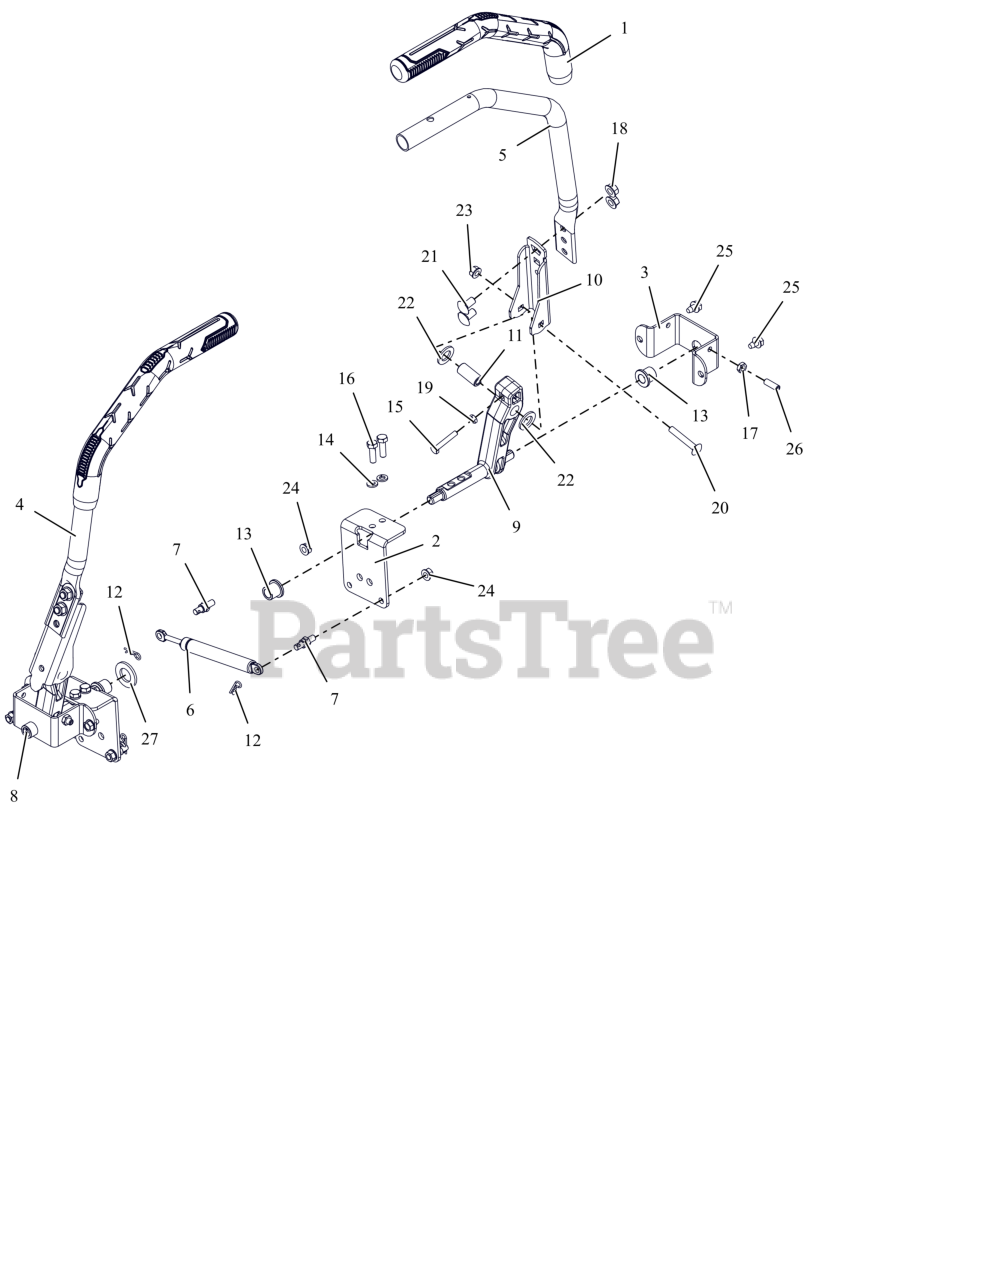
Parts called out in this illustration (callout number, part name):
1	GRIP, ARIENS HANDLEBAR
2	BRKT, STEEERING
3	BRKT, STEERING
4	HANDLE, STEERING-RH
5	HANDLE, STEERING-LH
6	DAMPER, STRAIGHT MOUNT
7	COUPLER, DAMPER MOUNT
8	ARM- STEERING-RH LOWER (MACH)
9	ARM- STEERING-LH LOWER (MACH)
10	ARM, CONTROL UPPER
11	BSHG-SLV .342 X .627 X 1.331
12	PIN, HAIR #213 .08X1.19 ZCC
13	BHSG-FLG .500X.750X.750X.125
14	WSHR,LK-REG .312X.078 ZCC
15	BLT, HEX .25-20X1.50F G5 ZCC
16	BLT, HEX .31-18X1.00 G8 ZCC
17	NUT-JAM .312-18 G2 ZCC
18	NUT-LK-TOP-FLG .375-16 GG ZCC
19	NUT-JAM .250-20 G2 ZCC
20	BLT, RHSSN .31-18X2.00 G5 ZCC
21	BTL,RHSSN .375-16 X 0.75 G5 FPB
22	WSHR, FRICTION
23	NUT,LK-CTR-FLG .31-18 GF ZCC
24	NUT-LK-TOP-FLG .312-18 GF ZCC
25	SCR,TAP .312-18X.50 HWH TR ZCC
26	SCR-SET, .312-18X1.000
27	WSHR, FLT .812X1.469X.134 ZCC
